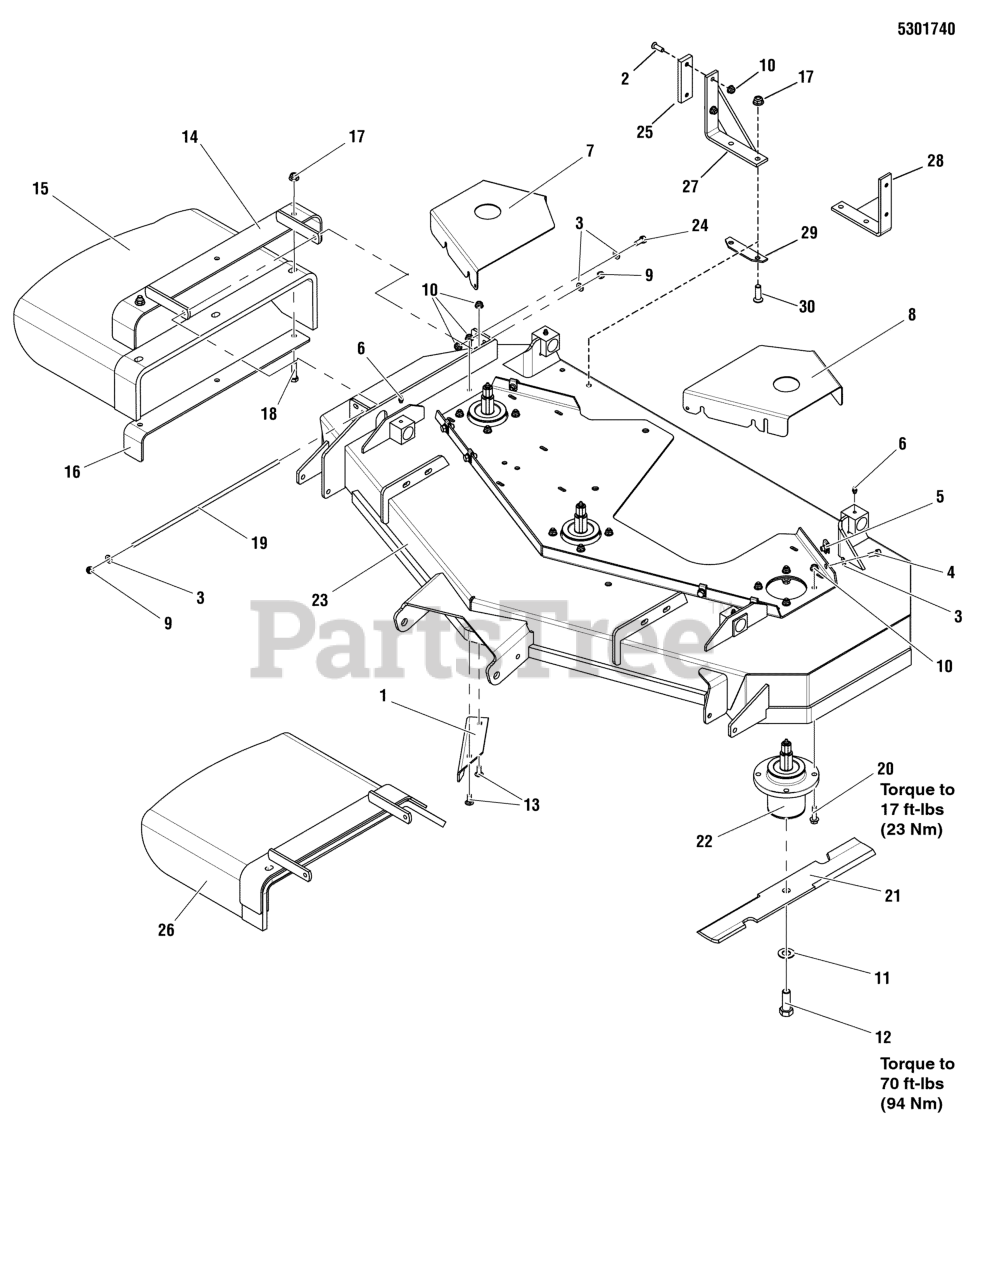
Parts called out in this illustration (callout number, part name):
1	PLATE, DEFLECTOR - BLK
2	SCREW, 5/16-18 X 1, PHILLIPS HD, BZ
3	WASHER, 5/16" SAE
4	BOLT, 5/16-18 X 1 GD5 YZ
5	BODY CLIP, 5/16-18-7GA MATERIAL
6	GREASE FITTING, 1/4-28 STRAIGHT
9	NUT, 5/16-24 HEX NYLON LOCK
10	NUT, 5/16-18 HEX NYLOCK FLANGE
11	WASHER, 5/8 GRADE 8, YZ
12	BOLT, 5/8-11 X 1-3/4 GD8
13	BOLT, 5/16-18 X 3/4, CARRIAGE
14	WELD, FRAME,CHUTE, 61" - RED
15	CHUTE, DISCHARGE, BEND RUBBER 61"
16	SUPPORT, DISCHARGE CHUTE - BLK
17	NUT, 3/8-16 HEX NYLOCK FLANGE
18	BOLT, 3/8-16 X 1-1/2" GD5 CZ
19	ROD, 5/16 X 13.75, TBE
20	BOLT, 5/16-18 X 1 1/4 FLANGE
22	ASSM, SPINDLE, LOW PROFILE
24	BOLT, 5/16-18 X 3/4 GD5
25	PAD, FRICTION, .375 X 1.25 X 4.00
26	KIT, DISCHARGE CHUTE, 61, SNP PRO
27	WELD, FRICTION PAD HOLDER, RH - RED
28	WELD, FRICTION PAD HOLDER, LH - RED
29	PLATE, BRACKET SUPPORT - RED
30	BOLT, Carriage, 3/8-16 X 1
